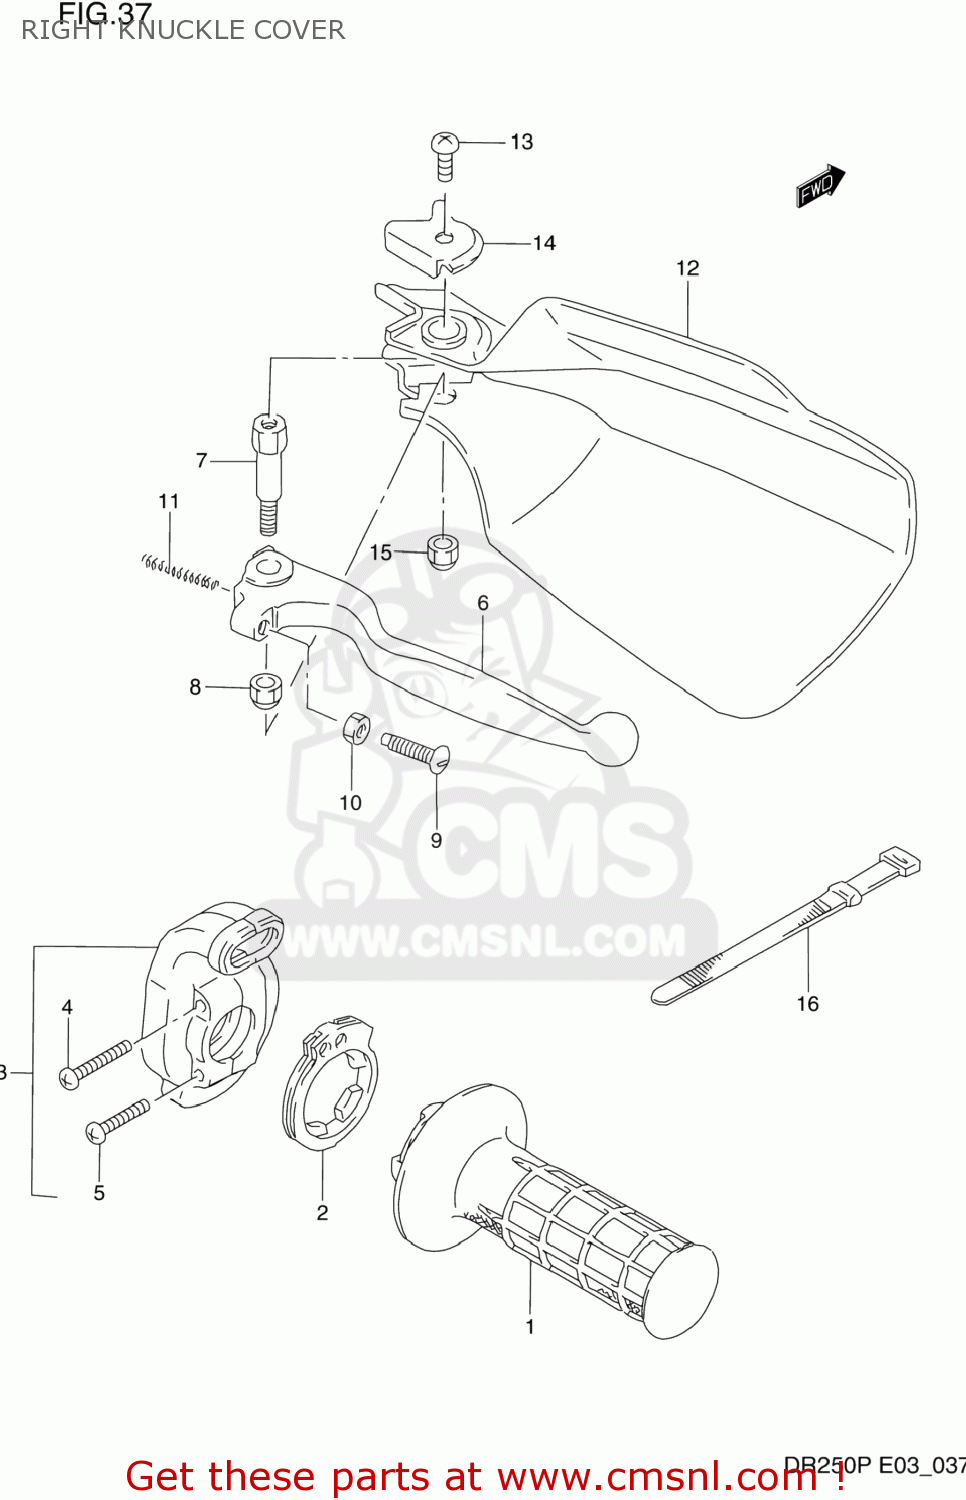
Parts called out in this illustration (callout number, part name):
1	GRIP,THROTTLE
2	ROTOR,THROTTLE GRIP
3	CASE ASSY,THROTTLE
4	SCREW(5X25)
5	SCREW 5X20
6	LEVER,BRAKE
7	BOLT,BRAKE LEVER PIVOT
8	NUT 6MM
9	BOLT,ADJUST
10	NUT ,5MM
11	SPRING,RETURN
12	COVER,KNUCKLE,R
13	SCREW(5X10)
14	PLATE,KNUCKLE COVER,R UPR
15	NUT 6MM
16	CLAMP(L:120)
